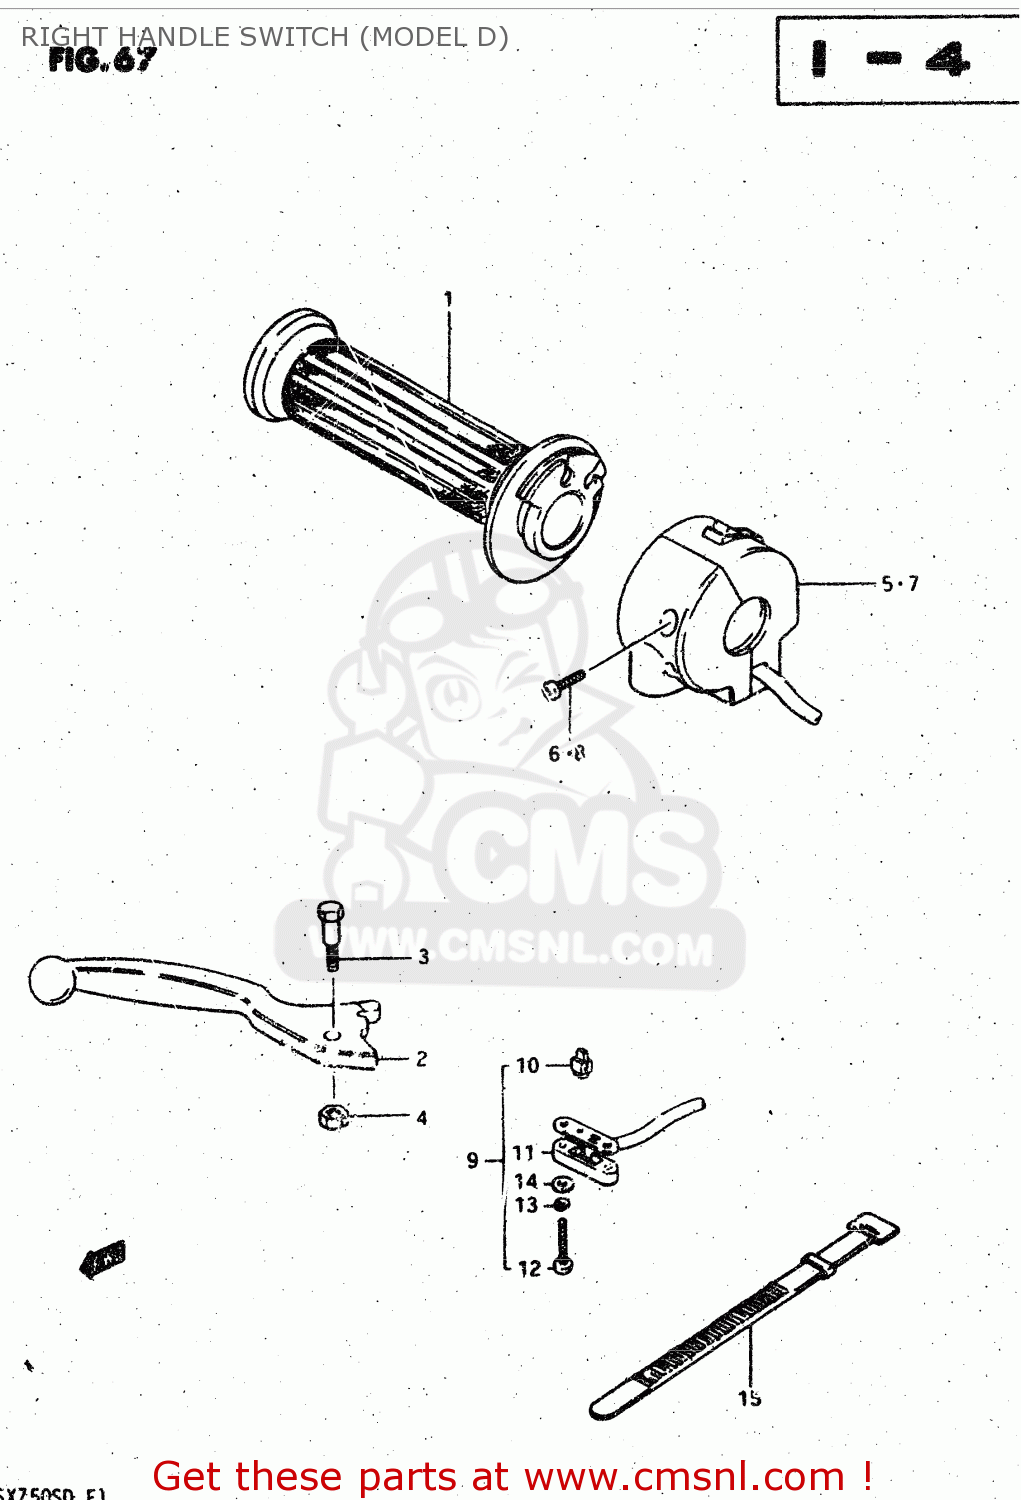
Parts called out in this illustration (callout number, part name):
1	GRIP,THROTTLE
2	LEVER,BRAKE
3	BOLT
4	NUT 6MM
5	SWITCH ASSEMBLY,HANDLE,RIGHT
6	SCREW
7	SWITCH ASSY, HANDLE RH
8	SCREW
9	SWITCH ASSEMBLY
10	CONTACT,SWITCH
11	COVER,FR BK TERMINAL BASE
12	SCREW
13	LOCK WASHER
14	WASHER
15	CLAMP(L:120)
